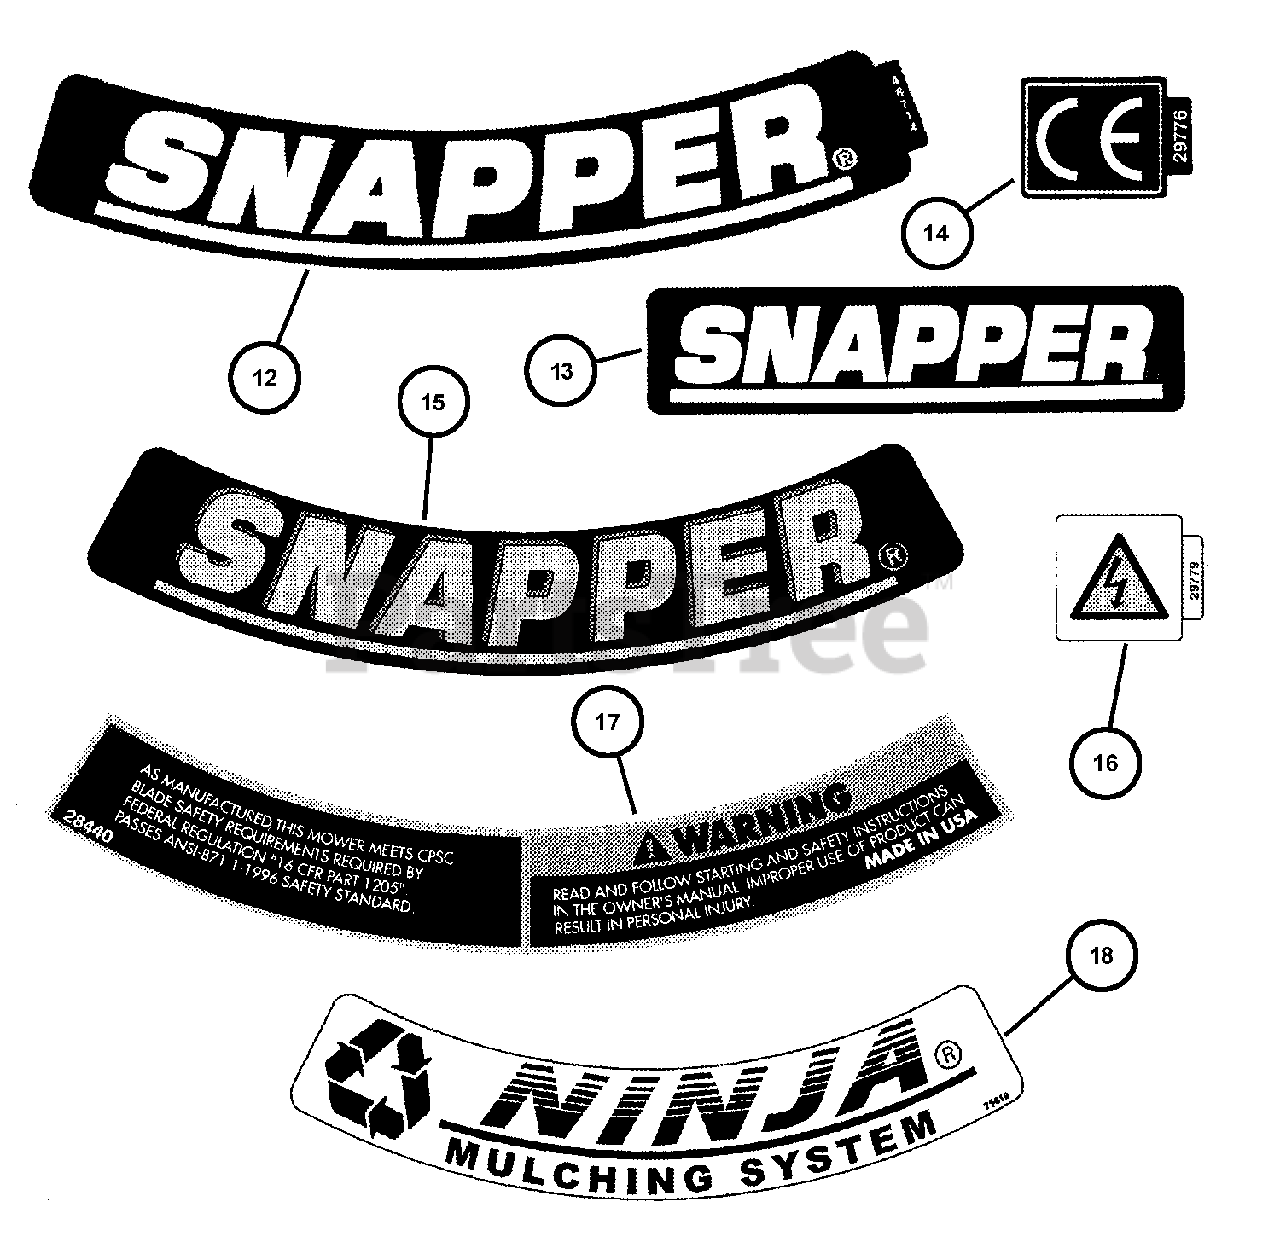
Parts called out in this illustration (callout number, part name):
12	DECAL, SNAPPER (Deck)
13	DECAL, SNAPPER
14	DECAL, Euro Community (CE)
15	DECAL, SNAPPER (Commercial)
16	DECAL, Spark Plug International Symbol
17	DECAL, Deck Warning
18	DECAL, Ninja
